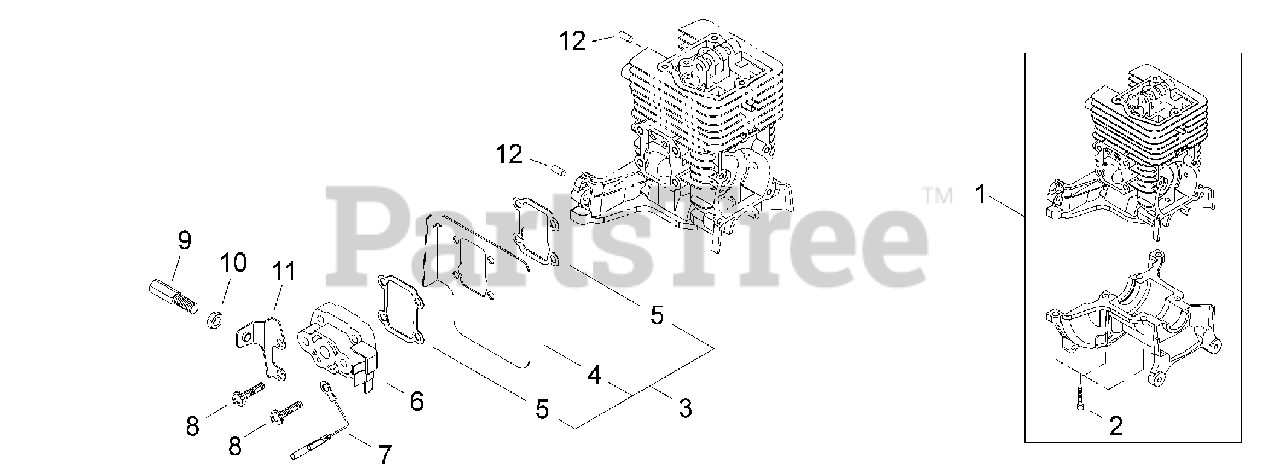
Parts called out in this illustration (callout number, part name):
1	CYLINDER & CRANKCASE ASSY
2	BOLT 5×16
3	SHIELD ASSY, INTAKE HEAT
4	HEAT SHIELD, INTAKE
5	GASKET, EXHAUST
6	INSULATOR WITH REED VALVE
7	LEAD - GROUND L= 110 MM
8	SCREW M5×22
9	ADJUSTER, THROTTLE CABLE
10	NUT, ADJUSTER LOCK M6
11	BRACKET, THROTTLE CABLE
12	PIN, LOCATING Ø4×8
